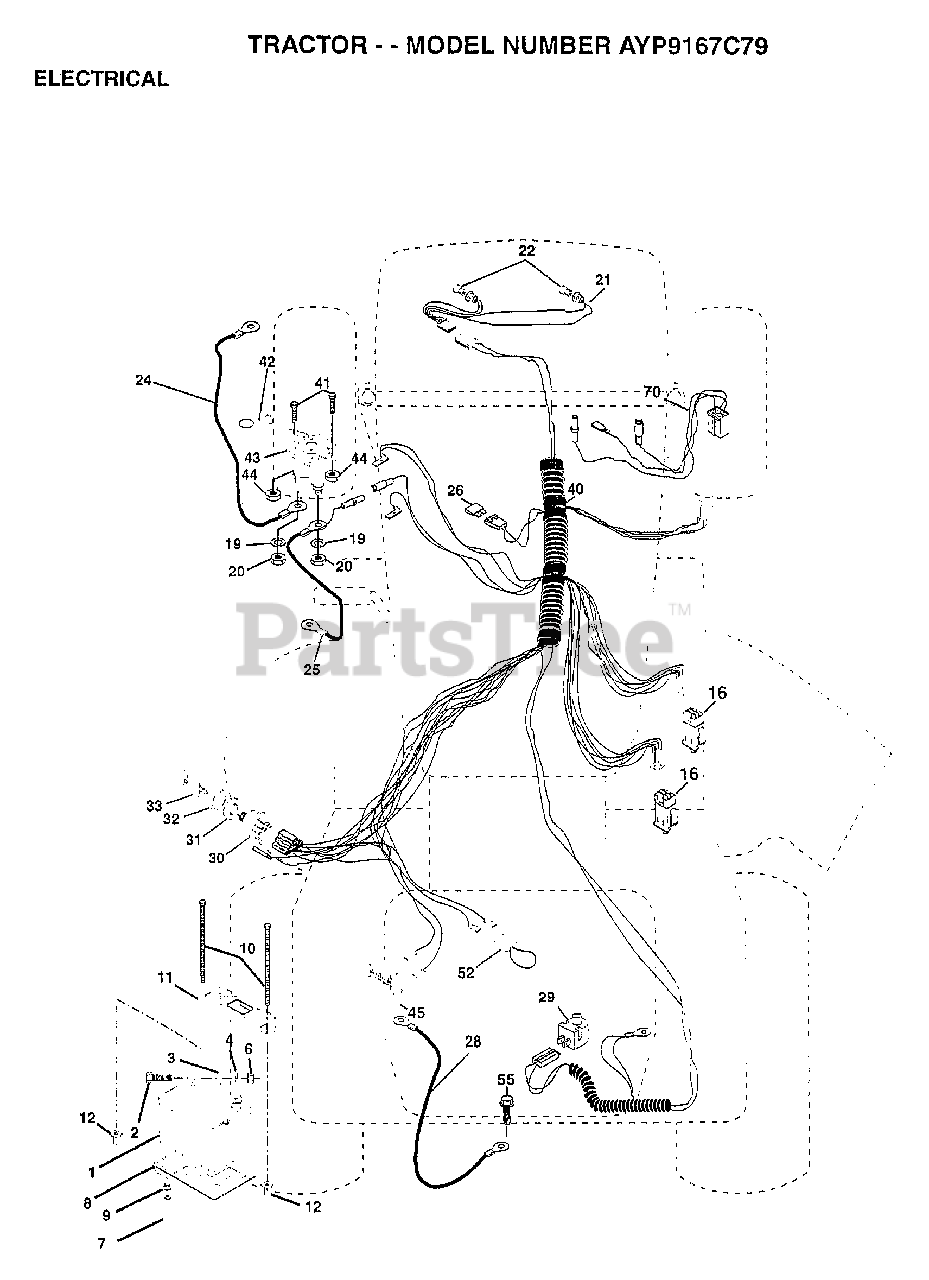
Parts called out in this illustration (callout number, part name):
2	BOLT LT
3	WASHER
4	LOCKWASHER
7	"DRAIN TU T, BATT"
8	"TRAY T, BATTERY"
9	HOSE CLAMP T
11	HOLDDOWN BATTERY
16	SWITCH INTERLOCK
20	NUT
21	"HARNESS,LIGHT SOC"
22	HEADLAMP BULB
24	"CABLE T, BATTERY"
25	CABLE.6GA.22W/16W
26	FUSE HYT
28	CABLE.GRND.6GA.21
29	SWITCH SEAT
30	SWITCH IGN 4POS
31	NUT IGNITION
32	COVER KEY SWITCH
33	KEY
40	HARNESS-IGNITION
41	BOLT HXHD FIN
44	NUT HXKEP 1/4X20
45	AMMETER
52	PROTECTION LOOP
55	SCREW LT
70	HARNESS ENGINE
